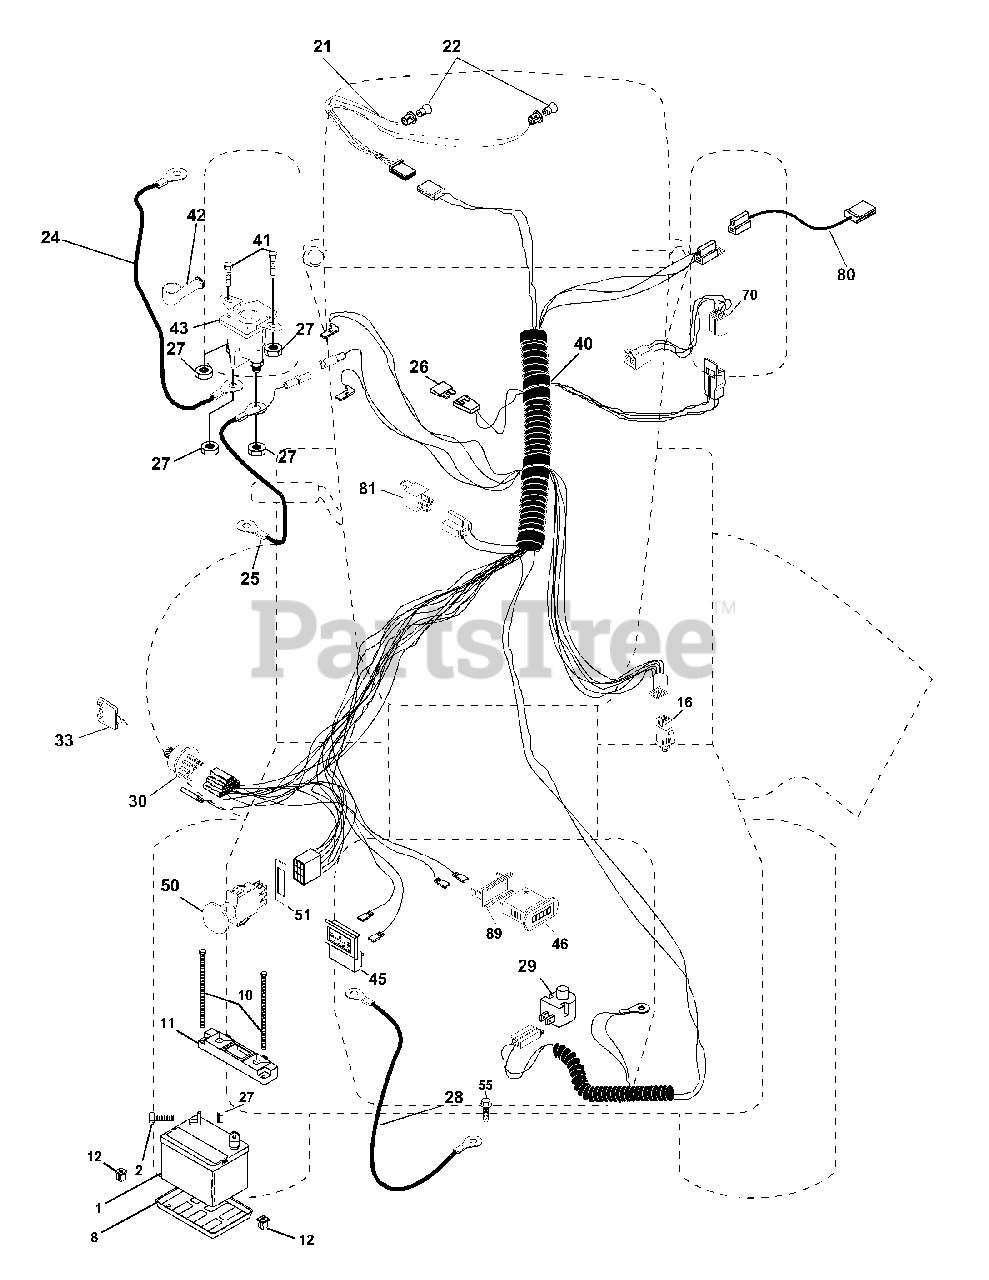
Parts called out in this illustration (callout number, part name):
1	Battery 12 Volt 25 AMP
2	Bolt Hex Hd 1/4-20unc X 3/4
8	Tray Battery 7.80 x 5.25 Blk
10	Bolt Btr Frt 1/2-20 x 7.5 Zinc
11	Holddown Battery Front Mount
12	Nut Push Nylon 1/4" Battery Frt
16	Switch Interlock Push-In
21	Harness Asm Light W/4152j
22	Bulb Light #1156
24	Cable Battery 6 Ga 11" red
25	Cable Battery 6 Ga 44" red w/16 wire
26	Fuse 15 AMP
27	Nut Keps Hex 1/4-20 Unc
28	Cable Ground 6 Ga 21" black
29	Switch Plunger Nc Gray
30	Switch Ign
33	Key Ign Generic
40	Harness Ign.
41	Bolt Blk Fin Hex 1/4 - 20 x 1/2
42	Cover Terminal Red
43	Solenoid
45	Ammeter Rectangular 15 Amp
46	Meter Hour
50	Switch PTO 3PDT Black Delta
51	Ring Retainer PTO
55	Screw Thdrol 5/16-18 x 1/2 Tyt
70	Harness, Eng
80	Harness Clutch Evx
81	Relay Asm.
89	Bracket Snap-In Hourmeter
